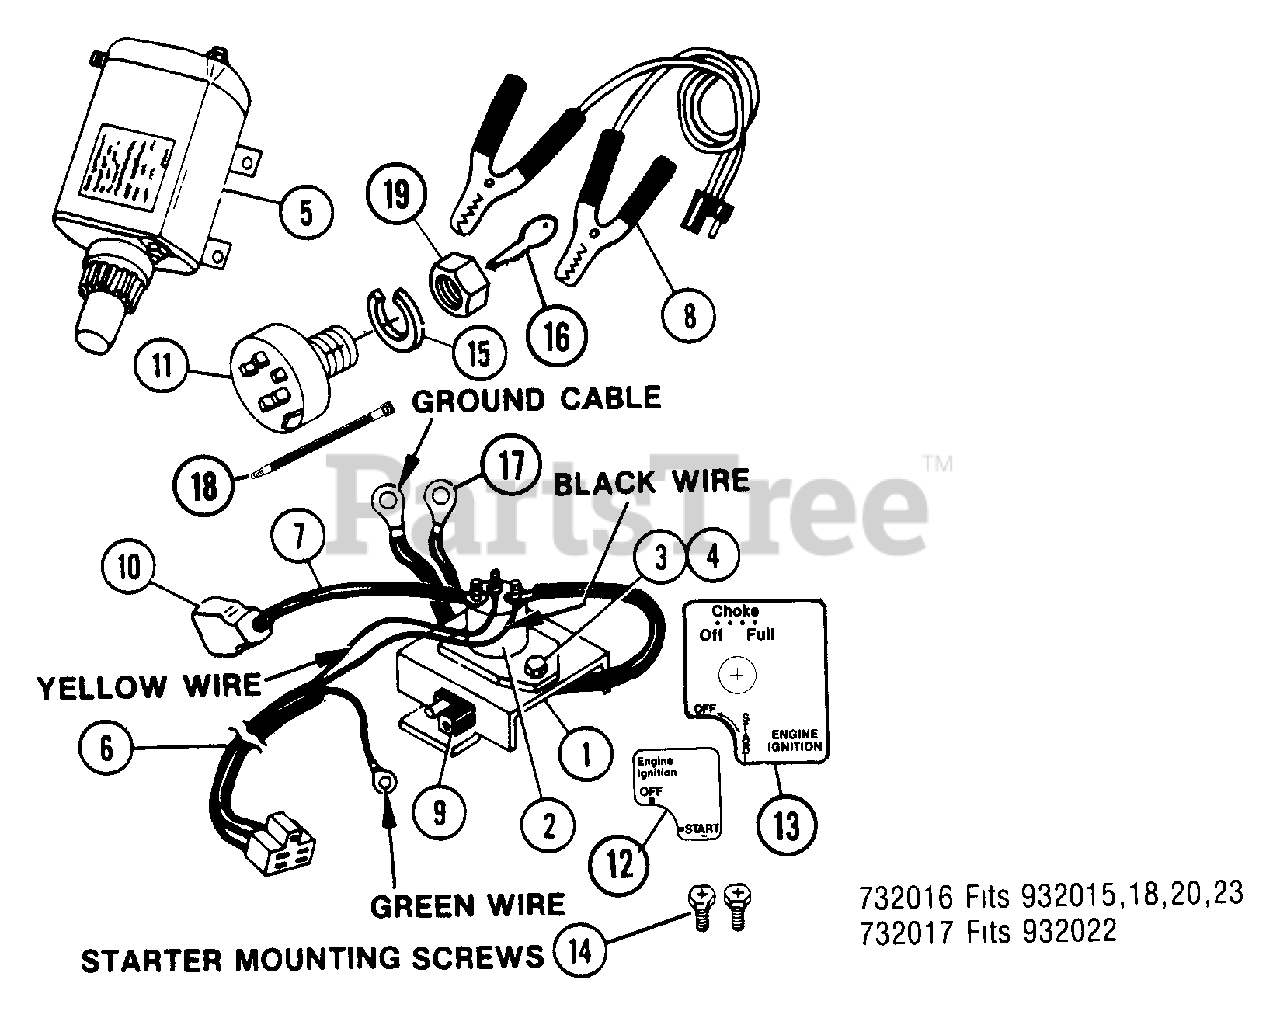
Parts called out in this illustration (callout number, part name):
1	BRACKET
2	SOLENOID
3	BLT-HEX .25-20X.50 PL GR2
4	NUT-LK-CTR .250-20 PL
5	Starter Motor
6	WIRING HARNESS
8	JUMPER CABLE W/CONNECTOR
9	ADAPTER LEAD W/CONNECTOR
10	INSULATOR
11	SWITCH ASSEMBLY
12	DECAL-SWITCH
13	DECAL-CHOKE & SWITCH
14	SCR-TAP .250-20X.62 CRHWH PL
15	WSHR-LK-INT .313X.030 PL
16	KEYS
17	GROUND WIRE
18	TIE DOWN
19	NUT .625-32 ALUM
